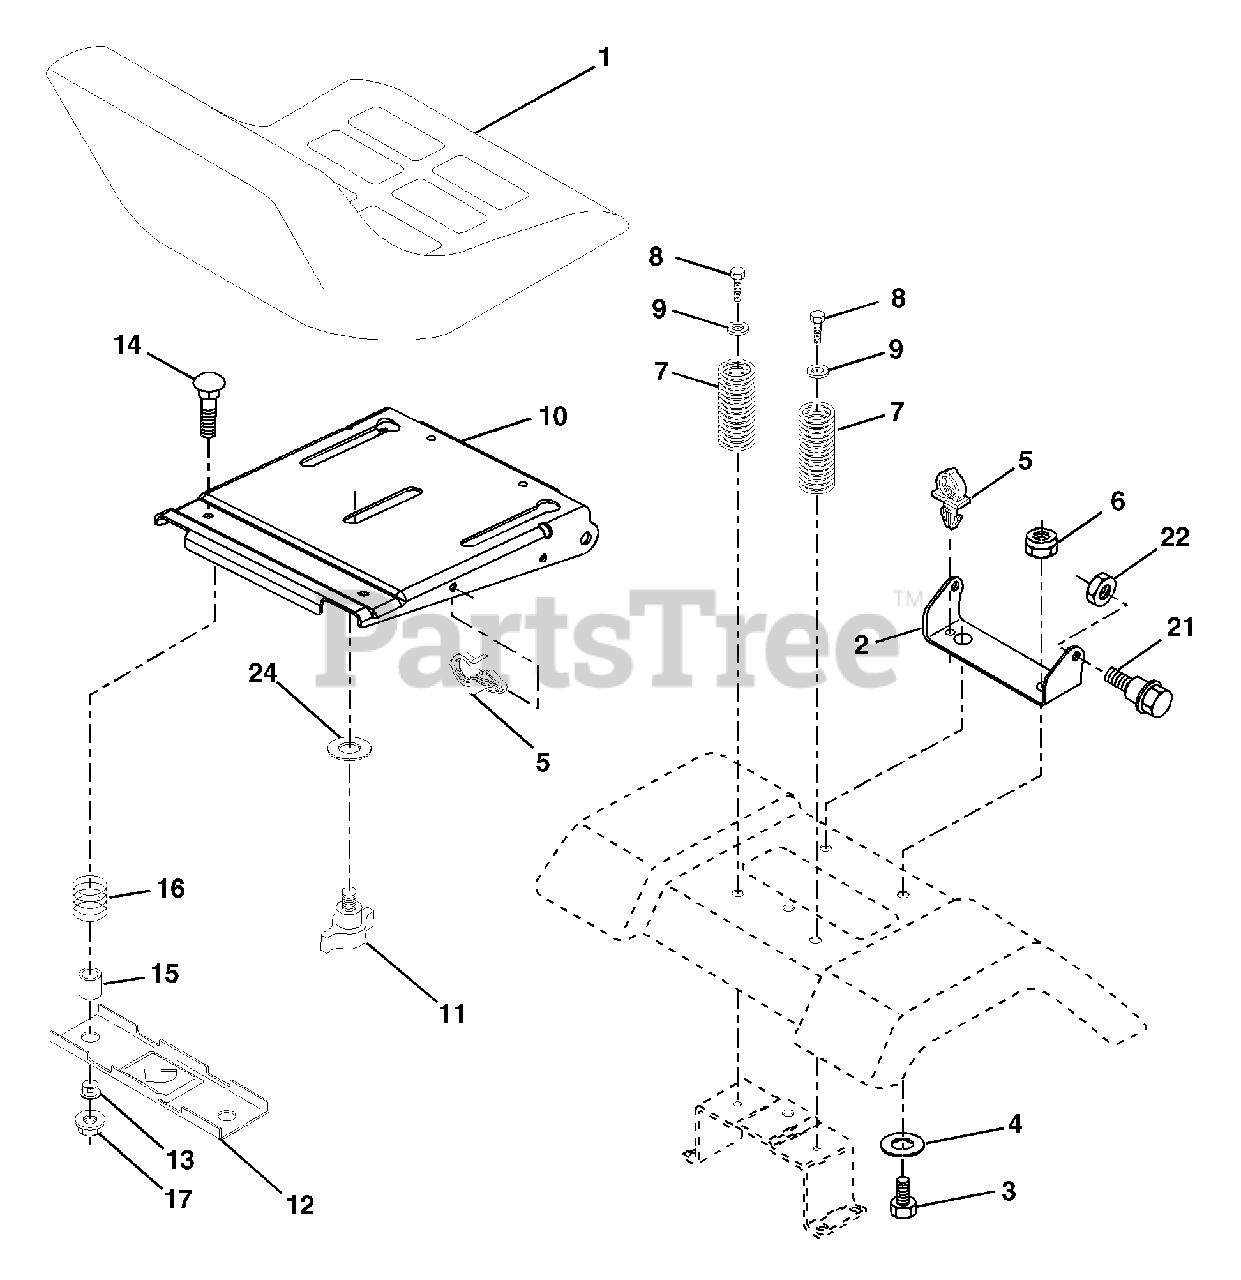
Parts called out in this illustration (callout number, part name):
2	Bracket Pivot Fender
3	Bolt Fin Hex 3/8-16 unc x 1
4	Washer 13/32 x 1 x 10 Ga.
5	Clip Push-In
6	Nut Hex w/Ins. 3/8-16 unc
7	Spring Seat Cprsn 2 250 Blk Zi
8	Screw 3/8-16 x 1.5 Smgml
9	Washer 13/32 x 1 x 14 Ga.
10	Pan Seat
11	Knob Seat
12	Bracket Mounting Switch
13	Bushing Snap Blk Nyl 50 Id
14	Bolt Rdhd Sqnk 1/4-20 x 1-1/2
15	Spacer Split 28x 88
16	Spring Cprsn
17	Nut Lock 1/4 Lge Flg Gr. 5 Zinc
21	Bolt Shoulder 5/16-18 unc
22	Nut Hex Lock W/Ins 5/16-18
24	Washer 17/32 x 1-3/16 x 12 Ga.
